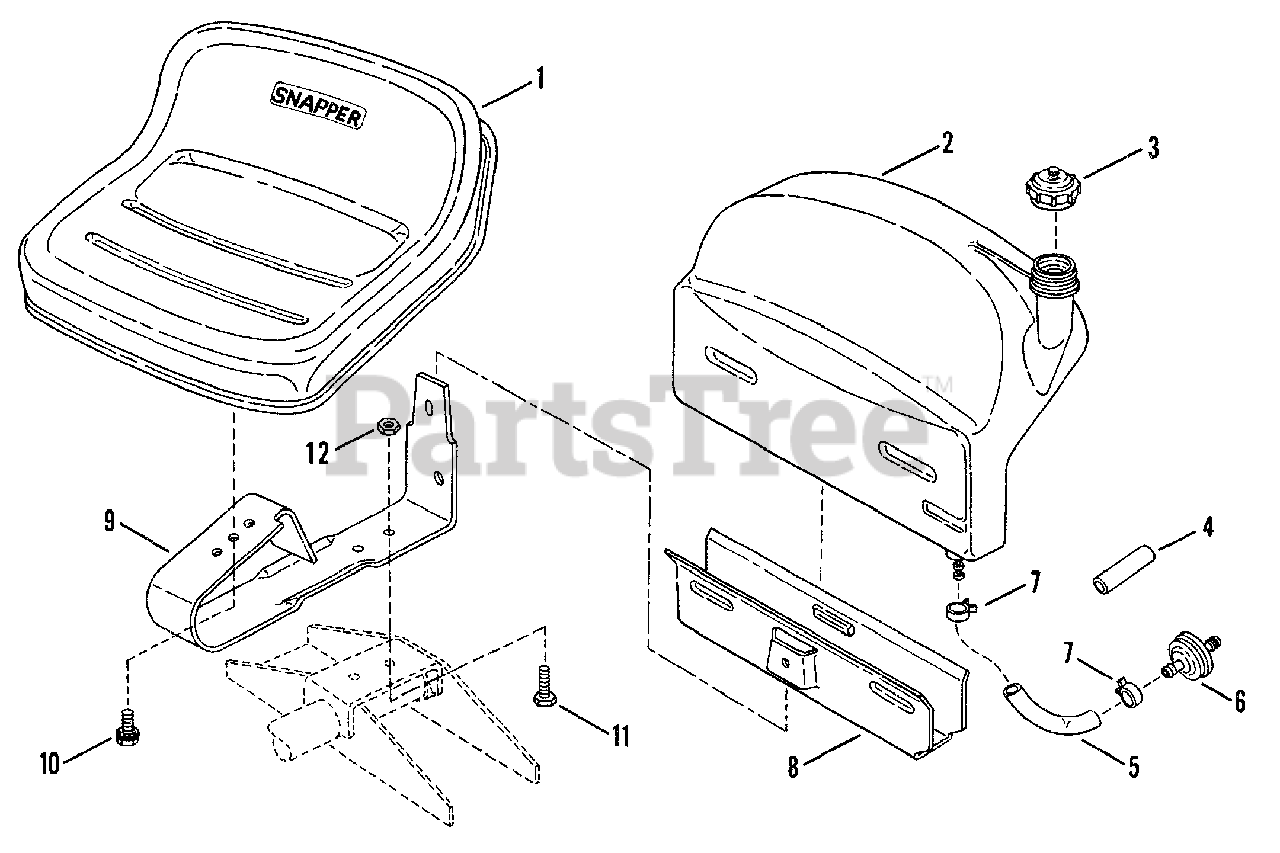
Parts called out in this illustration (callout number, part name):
1	SEAT, Operator
2	ASSEMBLY, Fuel Tank
3	CAP, Fuel Tank
4	HOSE, Fuel, 3"
5	HOSE, Fuel, 7"
6	FILTER, Fuel, In-Line
7	CLAMP, Fuel Line
8	BRACKET, Fuel Line
9	SPRING, Operator's Seat
10	BOLT, 1/2-13x3/4" Hex Flange Lock
11	BOLT, 3/8-16x1 Flange Lock
12	NUT, 3/8-16 Hex Lock
